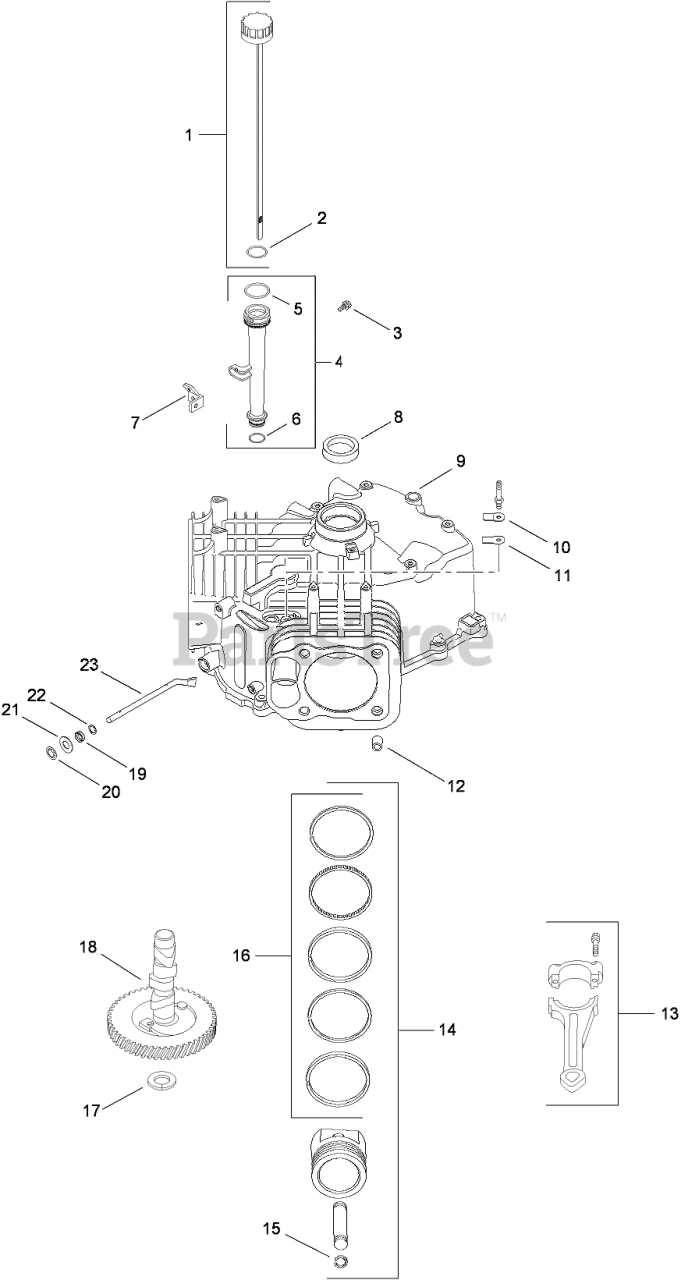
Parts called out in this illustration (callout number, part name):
1	DIPSTICK ASM (INCLUDES 2)
2	O-RING
3	SCREW-FLG, THD FRM (M5X0.8X13)
4	OIL FILL TUBE KIT (INCLUDES 5-6)
5	O-RING
6	O-RING
7	BRACKET-TUBE, OIL FILL
8	SEAL-OIL
9	Crankcase (Use Short Block)
10	RETAINER-REED, BREATHER
11	REED-BREATHER
12	PIN-LOCATING
13	ROD-CONNECTING (STD)
14	PISTON KIT W/RING SET (STD) (INCLUDES 15-16)
14	PISTON KIT W/RING SET (.25)
14	PISTON W/RING SET (.08)
15	RETAINER-PIN, PISTON
16	RING SET (STD AND .08)
16	Ring Set (.25)
17	SHIM-CAMSHAFT (WHITE .028)
17	SHIM-CAMSHAFT (BLUE .03)
17	SHIM-CAMSHAFT (RED .032)
17	SHIM-CAMSHAFT (YELLOW .034)
17	SHIM-CAMSHAFT (GREEN .036)
17	SHIM-CAMSHAFT (GRAY .038)
17	SHIM-CAMSHAFT (BLACK .04)
18	CAMSHAFT KIT (INCLUDES 25 357 14-S)
19	SEAL-CROSS SHAFT, GOVERNOR
20	RETAINER-RING
21	WASHER-FLAT (9MM)
22	WASHER-FLAT (11/32)
23	SHAFT-CROSS, GOVERNOR
24	LUBRICANT-CAMSHAFT
